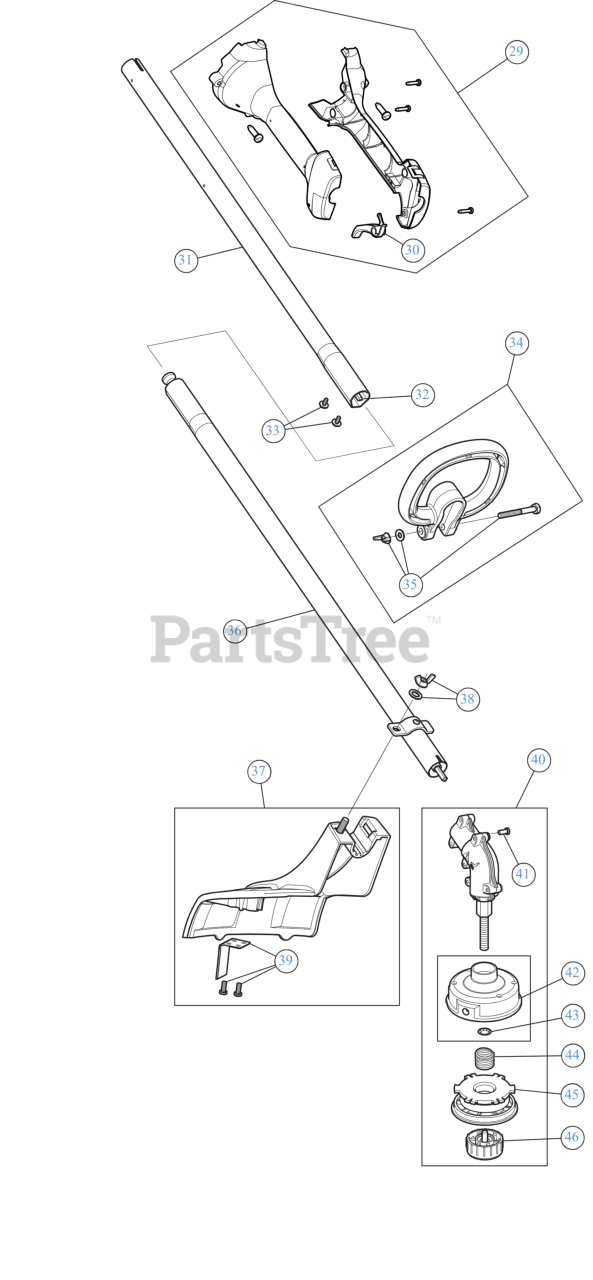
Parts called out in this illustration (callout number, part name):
29	THROTTLE GRIP ASSEMBLY
30	THROTTLE TRIGGER
31	UPPER BOOM ASSEMBLY
32	UPPER SHFT
33	SCREW 8-32X3/8
34	HANDLE
35	HANDLE HWD
36	LOWER BOOM ASSEMBLY
37	GUARD/BLADE ASM
38	BLADE GUARD MOUNTING HARDWARE
39	BLADE ASSEMBLY W/HDW
40	GEARBOX ASSEMBLY
41	SCREW 8-32X.437
42	REEL:OTR W/RET
43	RETAINER .625 OD 2
44	SPRING-SPOOL
45	REEL-INNER SPOOL
46	BUMP HEAD KNOB ASSEMBLY
